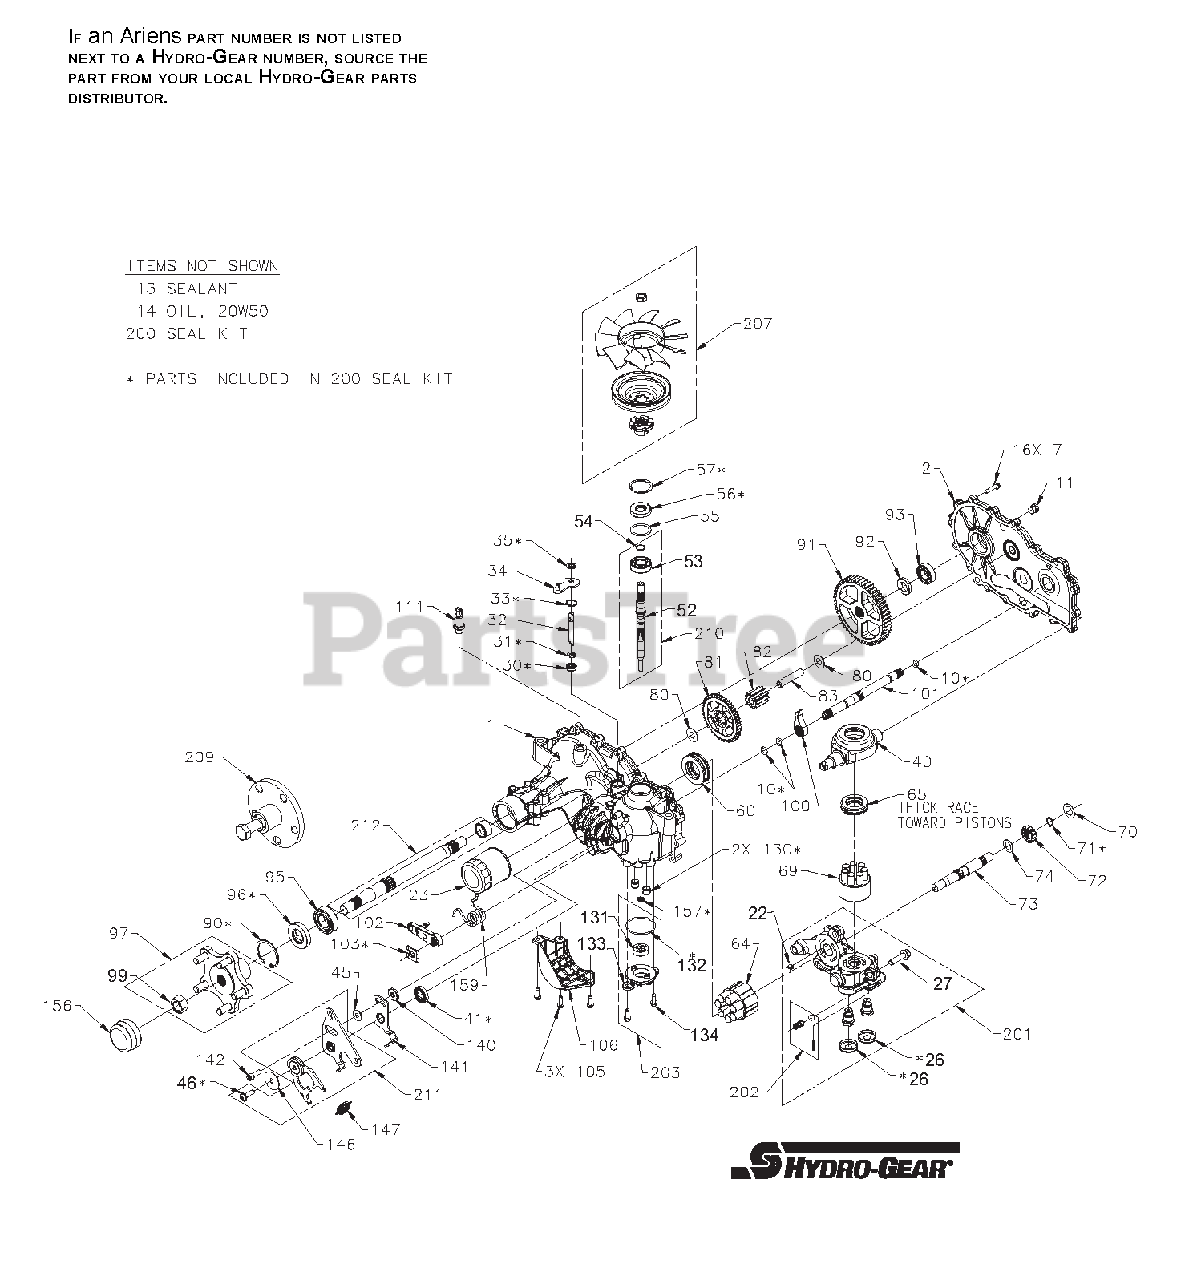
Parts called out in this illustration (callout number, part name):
1	Kit, Main Housing RH
7	HFHCS 1/4-20 X 1.25"
11	PLUG, STEEL (WITH SEAL)
22	PLATE, BYPASS
23	Filter, Oil
30	SEAL, LIP .375X.75X.25
31	RING. RETAINING
32	Rod, Bypass
33	RING, RET .750
34	Arm, Bypass
35	RING, RTNG .
40	TRUNNION, SWASHPLATE
45	WASHER
46	TWHCS 5/16-24 X 1.00
52	Shaft, Input
53	BRG, BALL 17X40X12
54	Ring, Ret Wire .561 ID
55	WASHER 1.23X1.56X.04
56	SEAL, LIP 17X40X7
57	RING, RET 1.56 INT
60	Bearing, Thrust
65	BEARING. THRUST 30 X 52 X 13
70	WASHER .63X1.0X.05
71	RING, RET 62 EXT
72	Gear, 13T, Steel
73	Shaft, Motor
74	WASHER .71 X 1.16 X .04
80	WASHER .5X1.0X.032
83	JACK SHAFT (PIN)
90	RING, RETAINING
95	BEARING, BALL 25.4 X 52 X 15
96	SEAL, LIP
99	NUT, HEX, LOCK 3/4-16
103	Clip, Retaining
105	HFHCS 1/4-20X.75
106	Guard, Filter, RH
111	Fitting, Str 9/16-18 SAE .5 Barb
130	Tube, Connecting
131	GEROTOR
133	Cover, Charge Pump
134	HFHCS 1/4-20X.75
142	SHCS 5/16-24X1 PATCH
146	WASHER
147	Spring, Extension Rtn - 34 lbs
200	Kit, Seal ( * - parts included in this kit)
NS	SEALANT TUBE 10.1OZ.
NS	20W50 Oil
